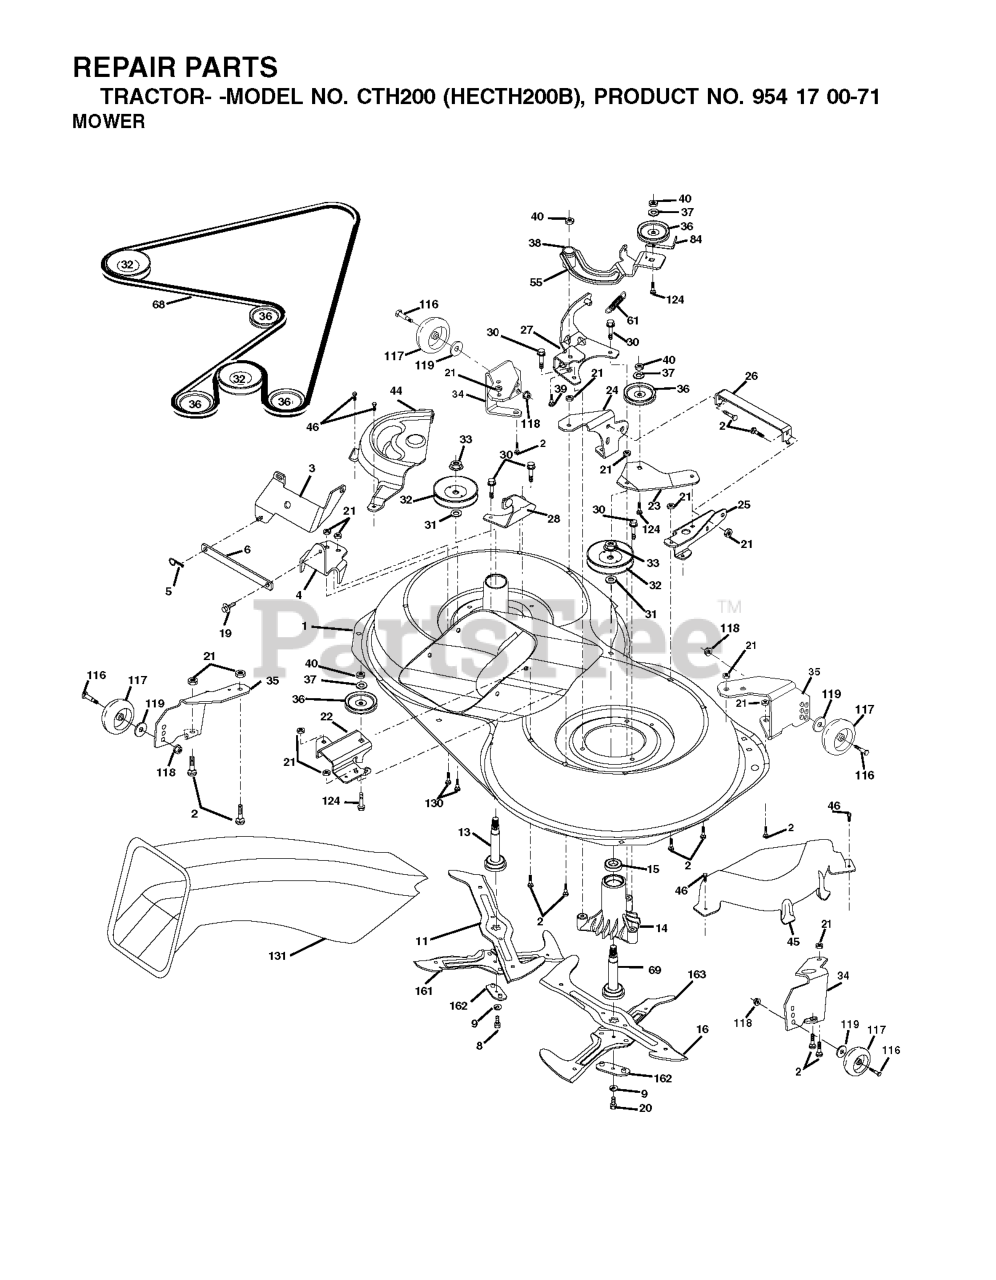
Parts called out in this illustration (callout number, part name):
1	Housing Asm. Mower 107 CRD
2	RP BOLT 5/16-18 X3/4 ZN/YEL GR
5	RETAINER SPRING
6	BAR.SWAY.92.CRD
8	BOLT.3/8-24X1.25 GR8
9	LOCKWASHER
11	BLADE.3N1.LH.CRD
13	SHAFT ASM VENT
14	HOUSING.MANDREL.VENTED (MACHD)
16	BLADE.3N1.RH.CRD
19	BOLT SHD 5/16-18
20	BOLT.3/8-24X1.25GR8. LHTHRD
21	LOCKNUT
22	BRACKET.IDLER.RR.107.CRD
23	BRACKET
24	BRACKET
25	BRACKET.SUSPENSION.RF.107.CRD
26	BRACE.SUPT.SUSP.FRT.CRD
27	BRACKET
28	BRACKET
30	SCREW, WASHER HEAD
31	WASHER
33	NUT, FLG TOPLOCK 9/16"
36	PULLEY.IDLER.4.25
37	WASHER
45	COVER.MANDREL.RH.CRD
46	SCREW.1/4-20X5/8
55	ARM.IDLER.107.CRD
68	HEX-BELT 107 MOWER
69	SHAFT.ASM.W/LWR.BRG.RH.THREAD
84	KEEPER, BELT IDLER
116	BOLT, SHOULDER
117	WHEEL GAGE DONUT
118	LOCKNUT
119	WASHER.5/16.FLAT.STE.STD.
124	BOLT.3/8-16X1.50
130	BOLT.CARR.SQNK.5/16-18UNC.X3/4
131	CHUTE BAGGER
163	BLADE.CROSS.RH.CRD.107
